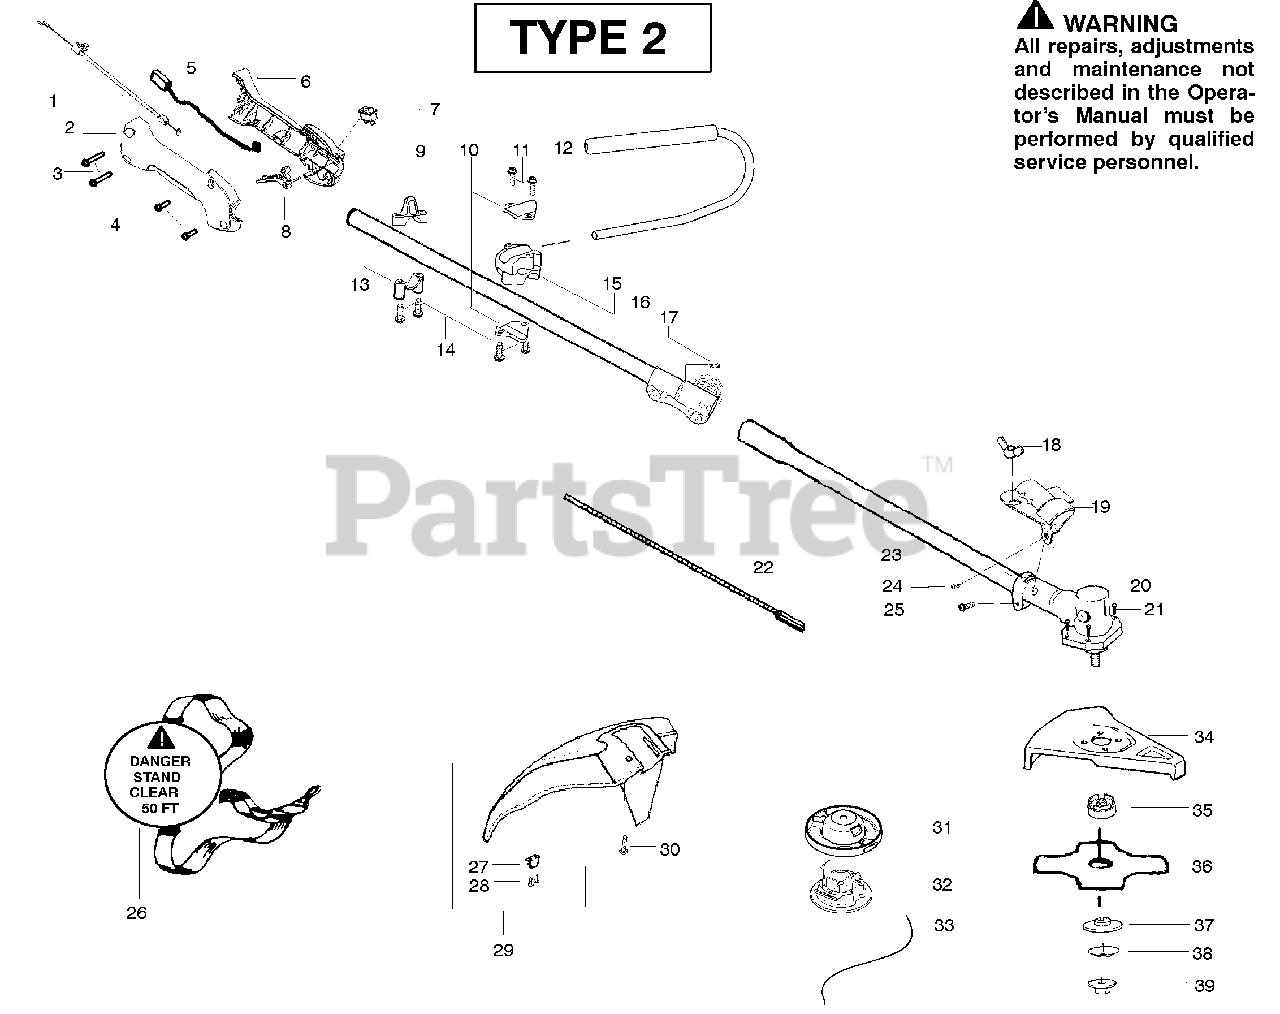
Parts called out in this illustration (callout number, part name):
2	Assy-Throttle Cable
2	Hsg.-Throttle-right
5	Assy-Wire
6	Hsg.-Throttle-left
7	Kit-Switch
8	Trigger-Throttle
9	Clamp-Harness (upper)
10	Clamp-Bracket
12	Assy.-Handlebar
13	Clamp-Harness (lower)
15	Clamp-Handlebar
16	Kit-Upper Shaft
18	Wingnut
19	Bracket-Shield
22	Shaft-Flex (lower)
23	Assy-Lower Shaft
26	Shoulder Strap
27	Limiter-Line
29	Kit-Shield Assy.
31	Head-Fixed line
32	Cap-Fixed Line
33	Accy-Line (12 pcs.)
34	Kit-Metal Shield
35	Dust cup
36	Accy.-Weed Blade
38	Washer-Belleville
39	Nut-Flange
